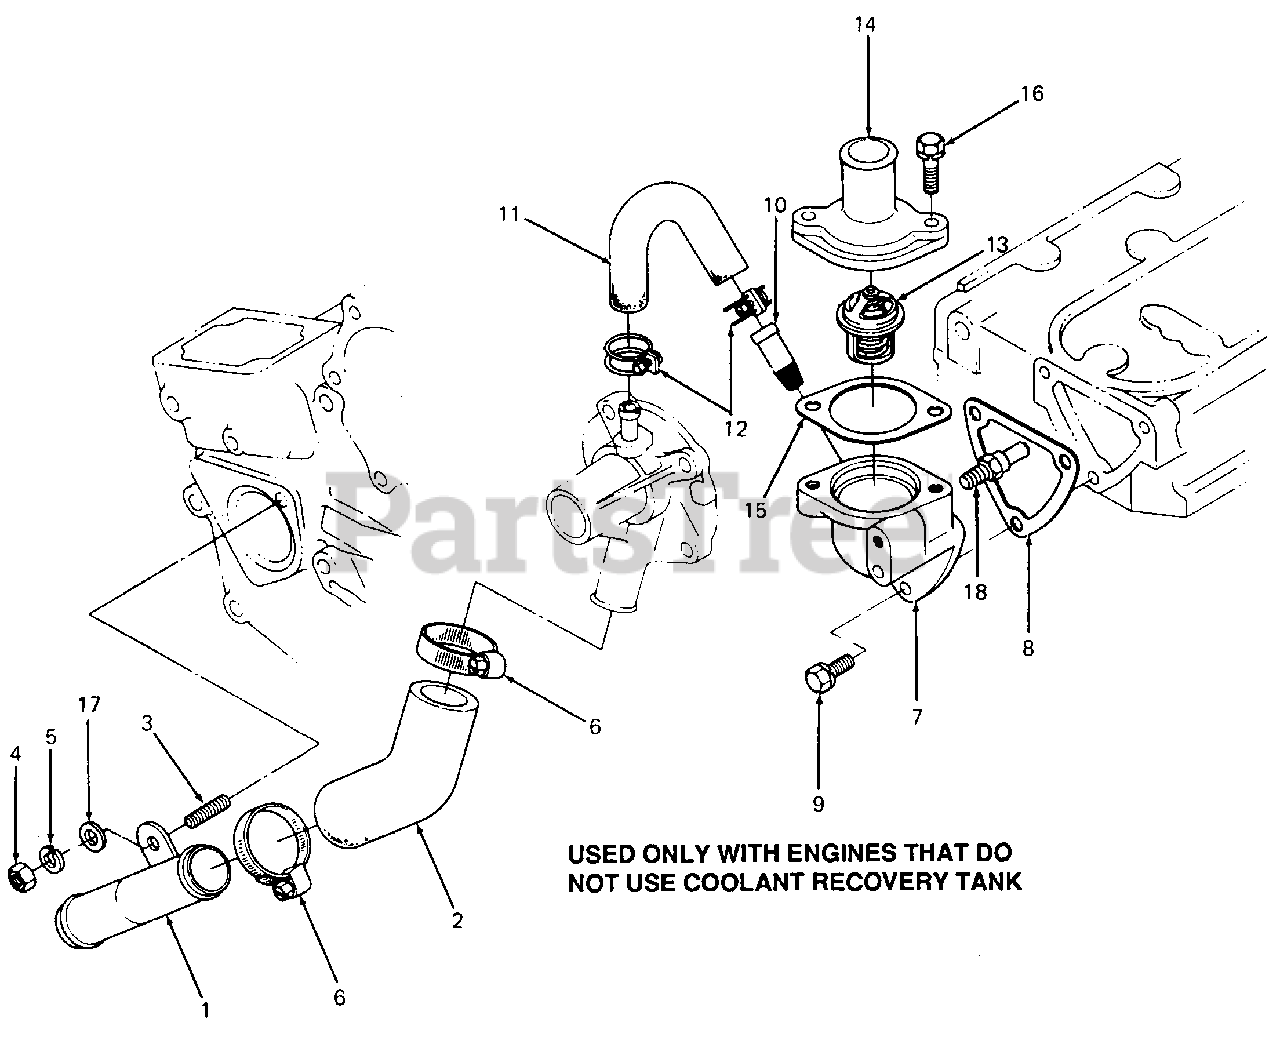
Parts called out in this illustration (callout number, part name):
5	Washer, Spring
7	Flange, Water
8	Gasket, Water Flange
9	Screw w/Washer
10	Pipe, Water Return
11	Pipe, Water Return
13	Thermostat
14	Cover, Thermostat
15	Gasket, Thermostat Cover
16	Screw w/Washer
18	Thermoswitch Assy
